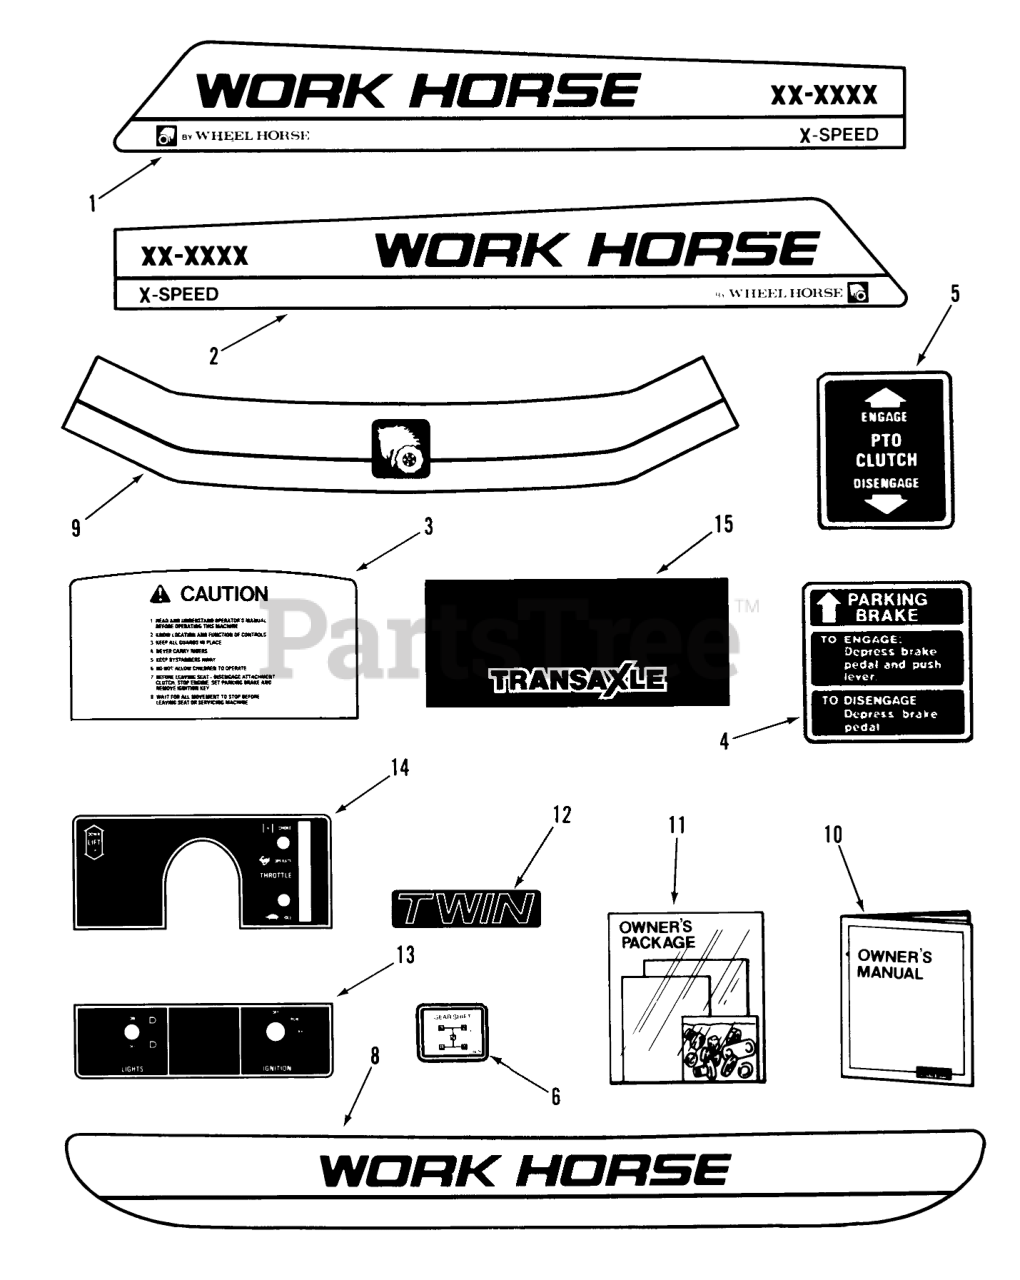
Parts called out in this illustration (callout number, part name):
1	Decal-Hood RH LT-832 Only
1	Decal-Hood RH LT-1136 Only
1	Decal-Hood RH LT-1137 Only
1	Decal-Hood RH LT-1637 Only
2	LH HOOD DECAL
2	Decal-Hood LH LT-1136 Only
2	Decal-Hood LH LT-1137 Only
2	Decal-Hood LH LT-1637 Only
3	DECAL - CAUTION
4	Decal Parking Brake
5	DECAL-PTO CLUTCH
6	DECAL-SHIFT
8	Decal Rear
9	DECAL - HOOD FRONT
10	Owner-s Manual-Tractor
10	Owner-s Manual-Mower
11	New Tractor Loose Parts Package LT-832 Only
11	New Tractor Loose Parts Package LT-1136, LT-1137 Only
11	New Tractor Loose Parts Package LT-1637 Only
12	Decal-Engine LT-1600 Only
13	DECAL-BACK PLATE-SWI
14	DECAL - LOWER DASH
15	DECAL - TRANSAXLE
